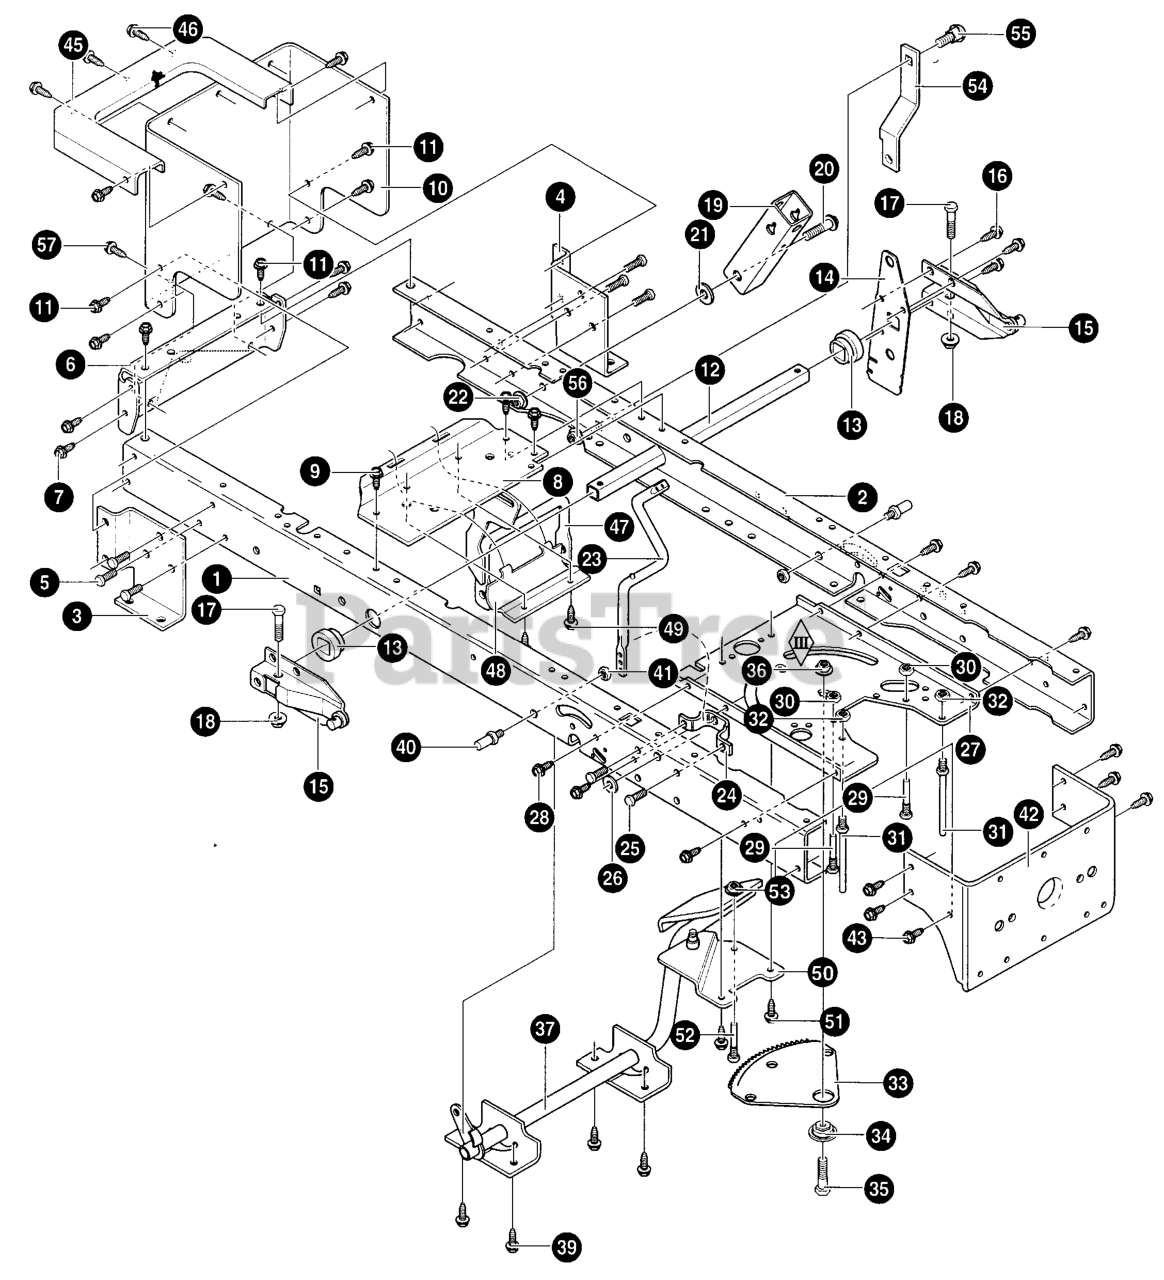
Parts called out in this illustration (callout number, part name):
1	FRAME, RAIL RH
2	FRAME, RAIL LH
3	BRACKET, TRANSAXLE RH
4	BRACKET, TRANSAXLE LH
5	SCREW, 5/16-18 x 0.75
6	HITCH PLATE
7	SCREW, 5/16-18 x 0.75
8	BRACKET, IDLER SUPPORT
9	SCREW 5/16-18X.75
10	PLATE, REAR
11	SCREW, 5/16-18 x 0.75
12	TUBE, LIFTER
13	BUSHING, LIFT TUBE
14	PLATE- LIFT ARM
15	ASSY LIFT ARM LEVER
16	SCREW, 5/16-18 x 0.50
17	SCREW, 5/16-24 x 1.25
18	NUT, 5/16-24
19	BRACKET, PIVOT
21	FLATWASHER
22	NUT, 3/8-16
23	CRANK, PTO (DRILLED)
24	BRACKET, BELLCRANK
25	SCREW, 5/16-18 x 0.75
26	FLATWASHER
27	PLATE, STEERING MOUNT
28	SCREW, 5/16-18 x 0.75
29	SCREW GUIDE 5/16-18
30	NUT, 5/16-18
31	SCREW - GUIDE
32	NUT, 5/16-18
33	SECTOR GEAR
34	BEARING, SECTOR GEAR
35	CAPSCREW, Hex Head, 5/16-18 x 1
36	NUT, 5/16- 8
37	ASSEMBLY, BRAKE LEVER
39	SCREW, 5/16-18 x 0.75
40	PIN, THREADED SHOULDER
41	NUT, 3/8-16
42	BRACKET, HANGER REAR
43	SCREW, 5/16-18 x 0.75
45	TOP, REAR PLATE
46	SCREW 10-24X.5
47	YOKE ASSY
48	CLAMP, TRUNNION PIVOT
49	SCREW, 51/6-18X.75
50	ASSY, IDLER INTERMEDIATE
51	BOLT, 5/16-18X0.5
52	SCREW GUIDE
53	NUT, 5/16-18
54	BRACKET, Torque Strap, LH
55	BOLT, 5/16-18X0.63
56	NUT, 5/16-18
57	SCREW, 5/16-18 x 0.50
